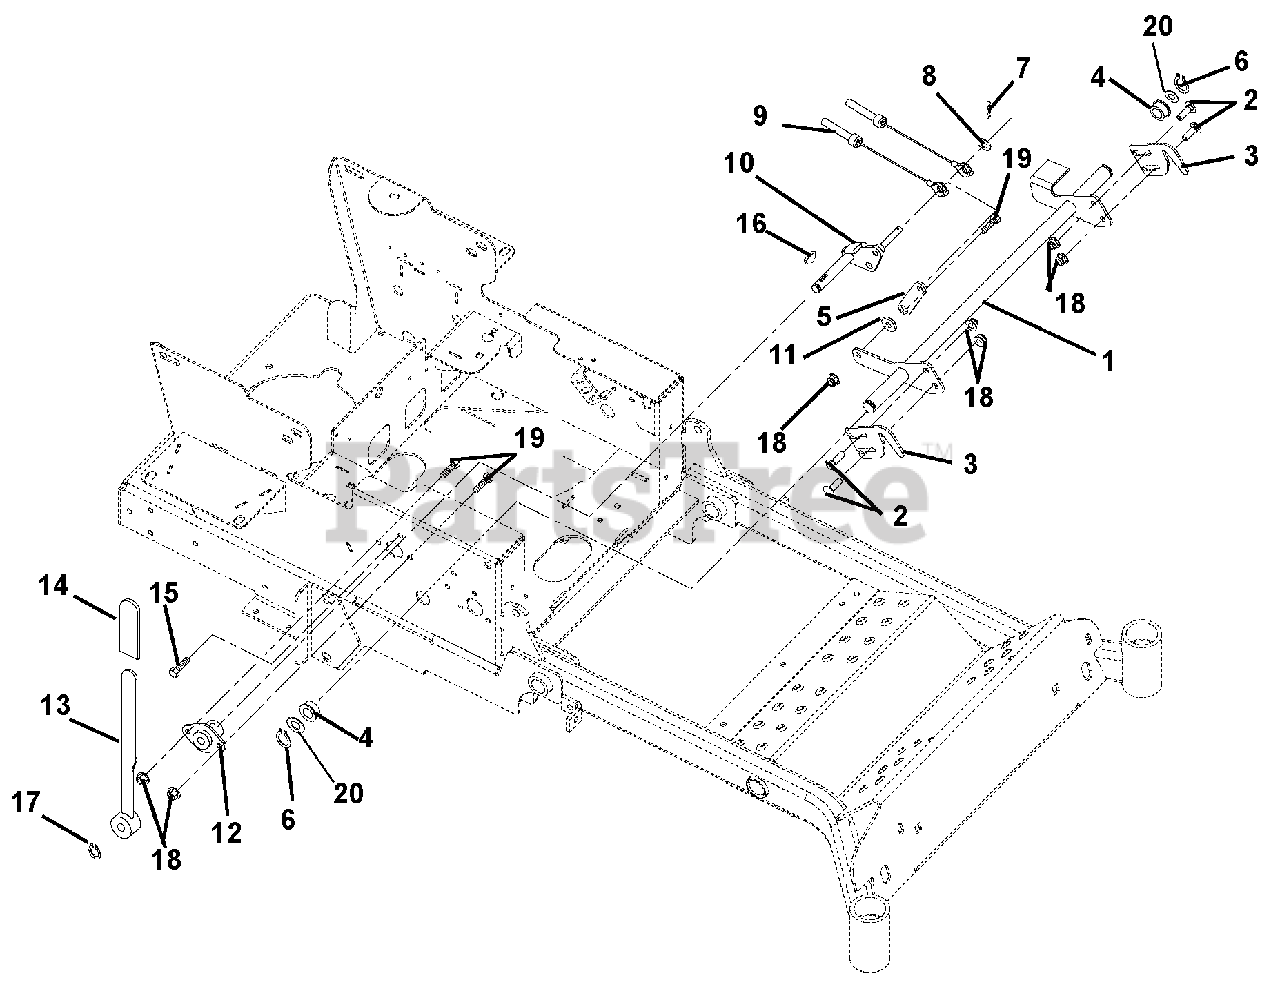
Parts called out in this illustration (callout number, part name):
1	Weldment, Neutral Lock Arm
2	Bolt, Round Head Square Neck .31-18 x 1.00 Grade 5
3	Neutral Lock Latch
4	Bushing, Flange .750 x 1.000 x .625 x 1.250
5	Plate, Neutral Interlock
6	Ring, Retaining-External .689 x .077
7	Pin, Hair-Internal .06 x .18 x .77
8	Washer, Flat-Steel .344 x .688 x .065
9	Cable, Brake Actuating
10	Weldment, Park Brake Arm
11	Bushing, Flange .325 x .499 x .26 x .88
12	Bushing, Flanged
13	Weldment, Parking Brake Lever
14	Grip, Parking Brake
15	Screw, Tapping .38-16 x 1.00 Hex Washer Head
16	Key, Woodruff .13 x .63
17	Ring, Retaining External .50 x .05
18	Nut, Nyloc Flange 5/16-18
19	Bolt, Hex .31-18 x 1.00 Grade 5
20	Washer, Flat-Steel .812 x 1.370 x .100
